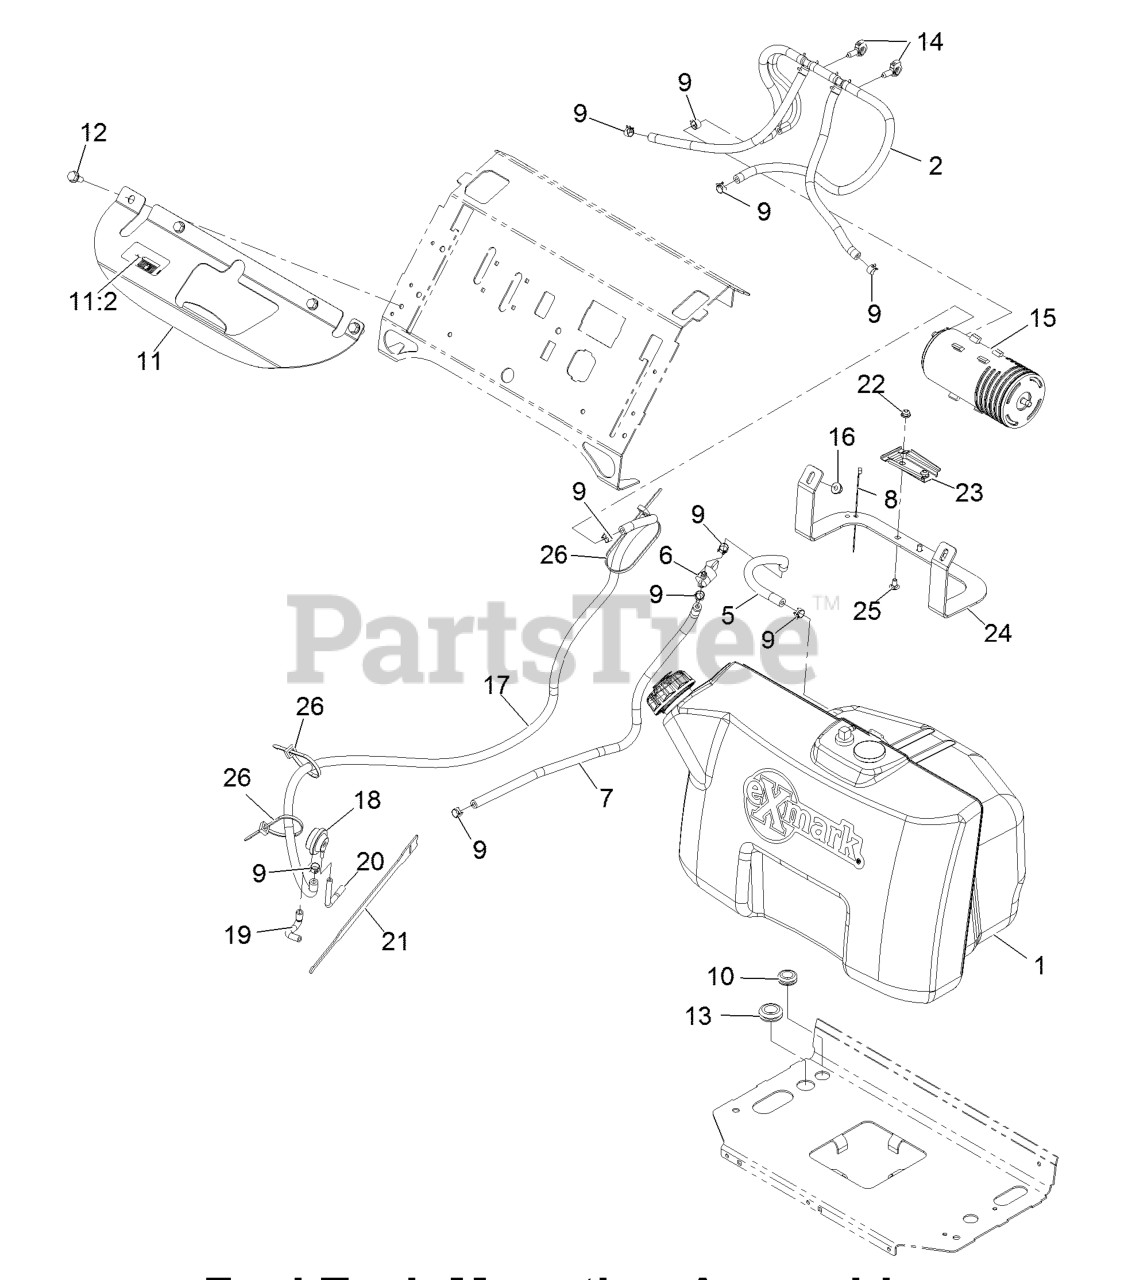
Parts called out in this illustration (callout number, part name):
2	VENT ASM
5	HOSE-FUEL
6	VALVE-FUEL
7	HOSE-FUEL
8	TIE-CABLE
9	CLAMP-HOSE
10	GROMMET
11	BRACKET-TANK
11:2	DECAL-FILL, FUEL
12	Screw-HWH 5/16-18 X 3/4 Tf
13	GROMMET
14	CLIP-HARNESS
15	CANISTER-CARBON, 800CC
16	NUT-HF, NI
17	HOSE-FUEL
18	VALVE-CONTROL, VACUUM
19	HOSE-VENT, FORMED
20	HOSE-VENT, FORMED
21	STRAP-VELCRO, CABLE TIE
23	BRACKET-CANISTER, CARBON
24	BRACKET,CANISTER MOUNTING
25	SCREW-CARR
26	TIE-CABLE
